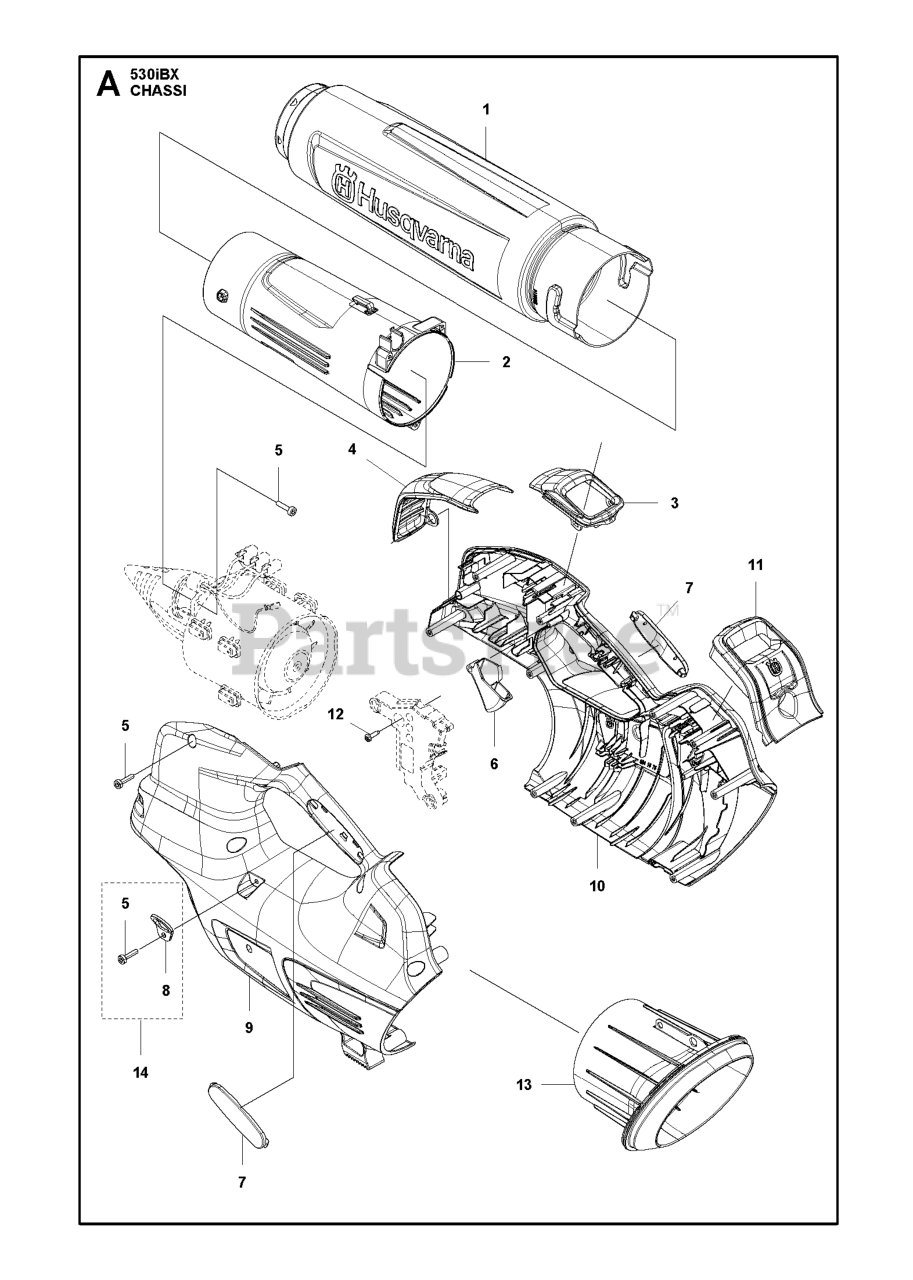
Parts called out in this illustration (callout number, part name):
1	TUBE ASSY NOZZLE SILENCER
2	TUBE FAN OUTLET
3	FRAME KEYPAD
5	SCREW
6	THROTTLE CONTROL
7	HANDLE INSERT
14	KIT EYELET
